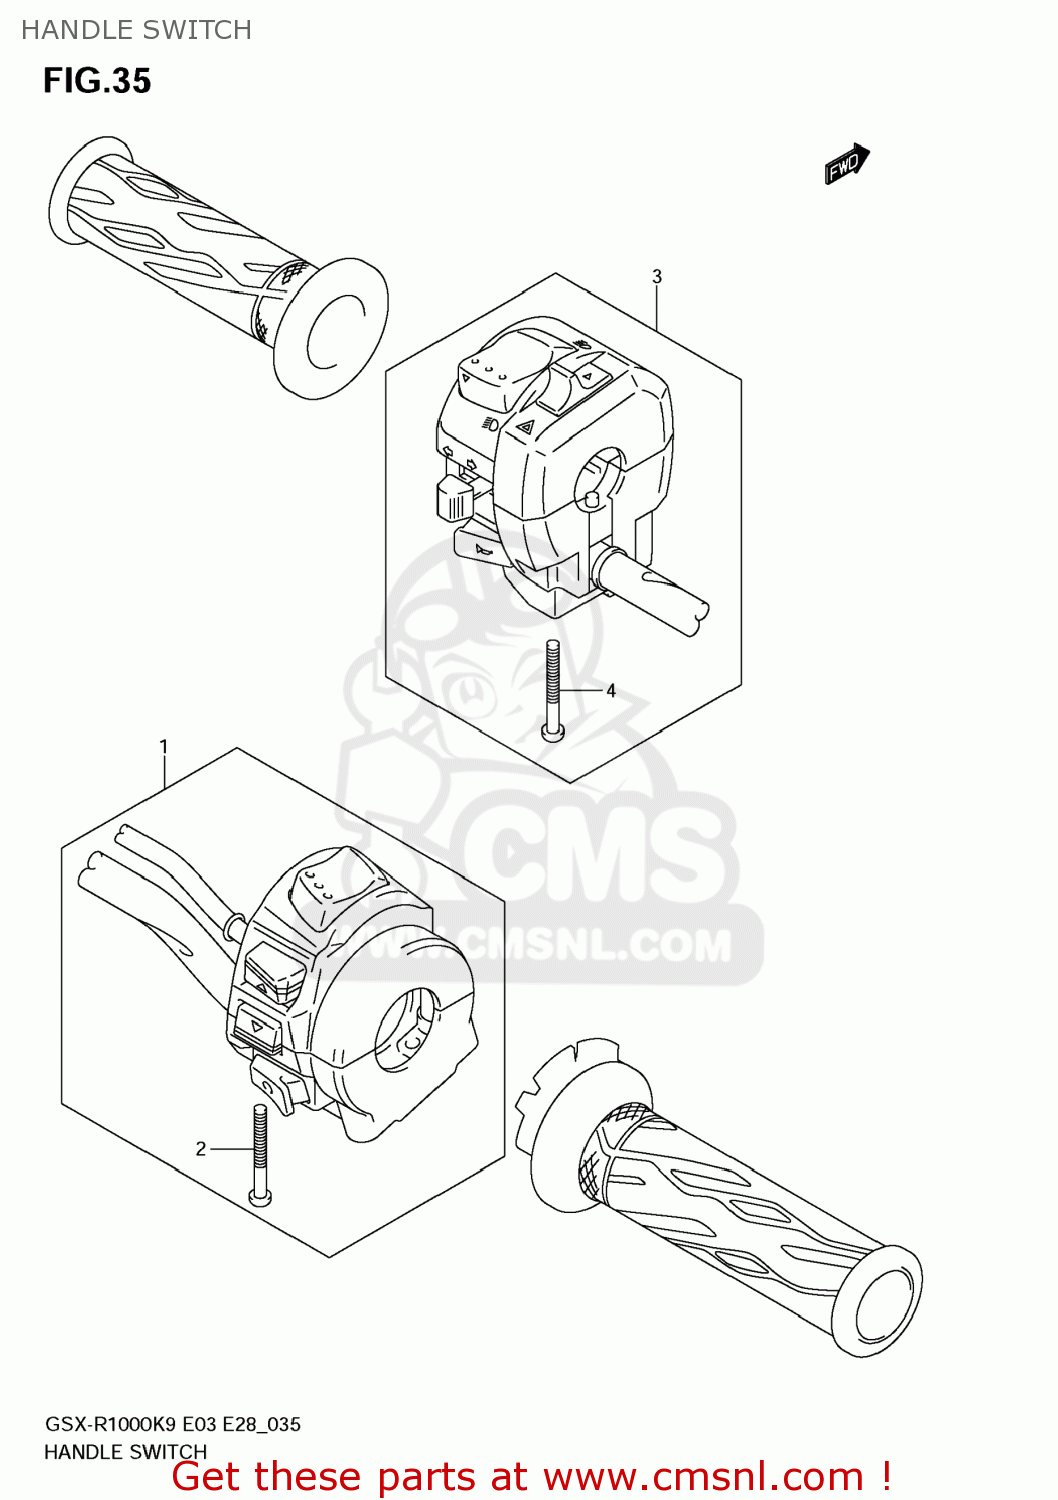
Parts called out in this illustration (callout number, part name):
1	SWITCH ASSY,HANDLE,R
2	SCREW
3	SWITCH ASSY,HANDLE,L
4	SCREW
